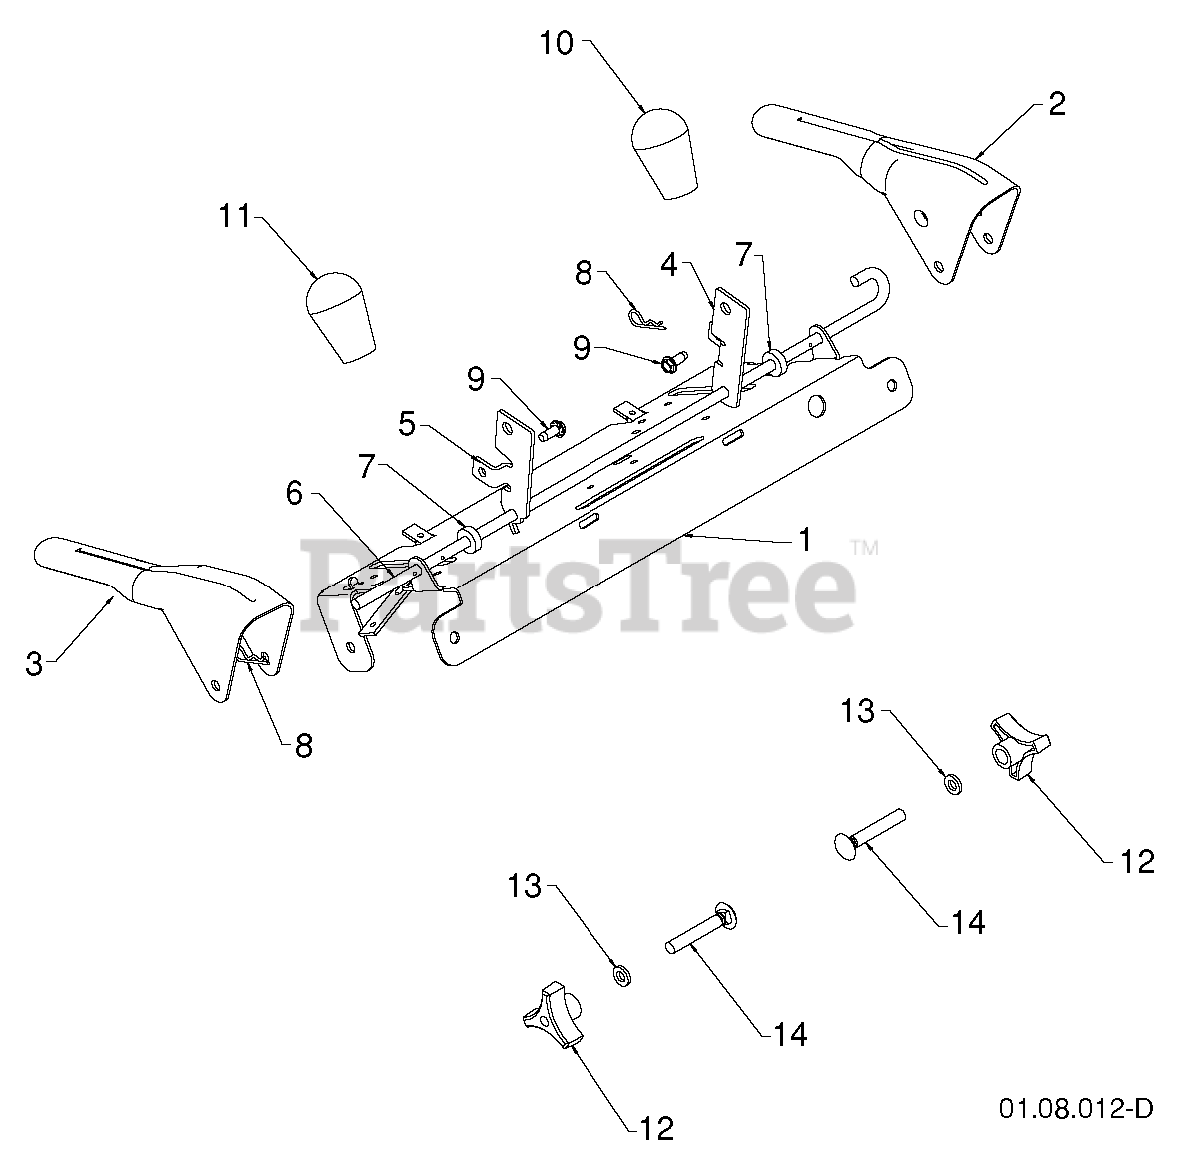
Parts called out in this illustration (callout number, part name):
1	PANEL.CONTROL.PNT.BLACK
2	LEVER.CONTROL.LH.BLACK
3	LEVER.CONTROL.RH.GREY
4	ARM.TRACTION.ROD.YZ
5	ARM.IMPELLER.ROD.SNOW
6	BAIL.CONTROL.INTERLOCK
7	SPACER.CONTROL.LEVER
8	SPRING RETAINER
9	SCREW 14-20 X 5/8
10	KNOB LEVER, BLACK
11	RED KNOB SHIFTER
12	KNOB.HANDLE.3/8.TRI-POINT.BLAC
13	WASHER
14	BOLT 3/8-16 X 2-1/4
